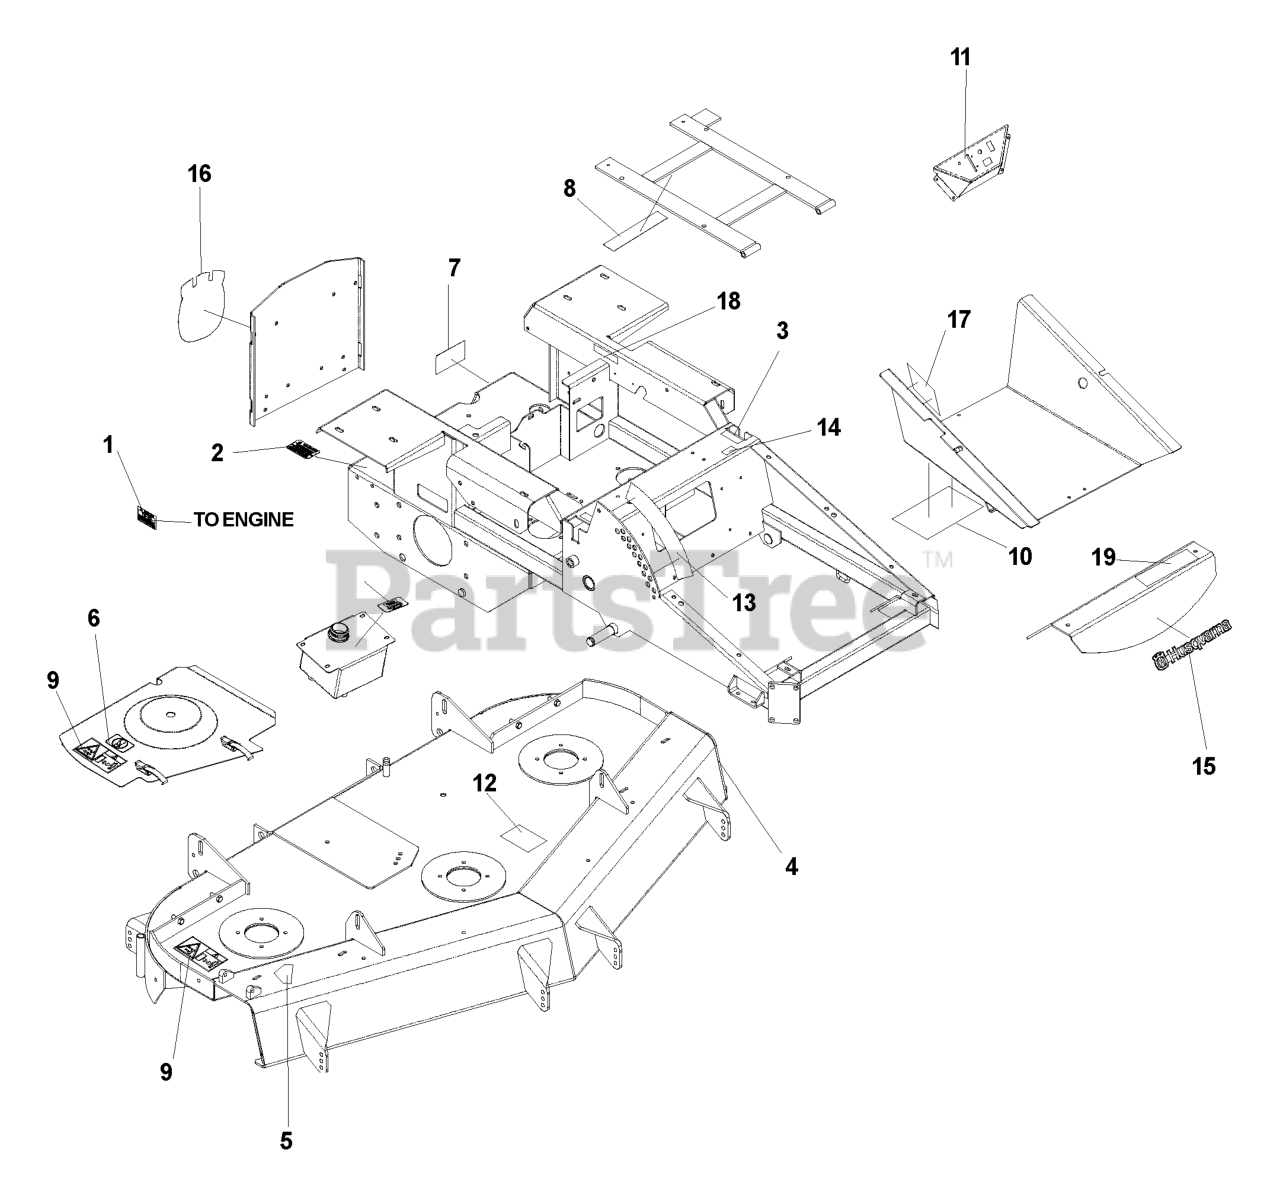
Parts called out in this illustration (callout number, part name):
1	DECAL, EXHAUST
2	DECAL, PROP 65
3	DECAL, MOTION CONTROL
4	DECAL, NASCAR
5	DECAL, WARNING
6	DECAL, EURO NO STEP
7	DECAL, EURO DANGER, BELT
8	DECAL, EURO BATTERY WARNING
9	DECAL, EURO SEVERING
10	DECAL, SERVICE
11	DECAL, CONSOLE
12	DECAL, BELT ROUTING
13	DECAL, HEIGHT ADJUSTMENT
14	DECAL, H.S.T.
15	DECAL, HUSQVARNA
16	DECAL, CROWN
17	DECAL, WARNING
18	DECAL, RELAYS
19	DECAL, IZ4217
19	DECAL, IZ4817
19	DECAL, IZ4821
19	DECAL, IZ5223
19	DECAL, IZ5225
19	DECAL, IZ6125
